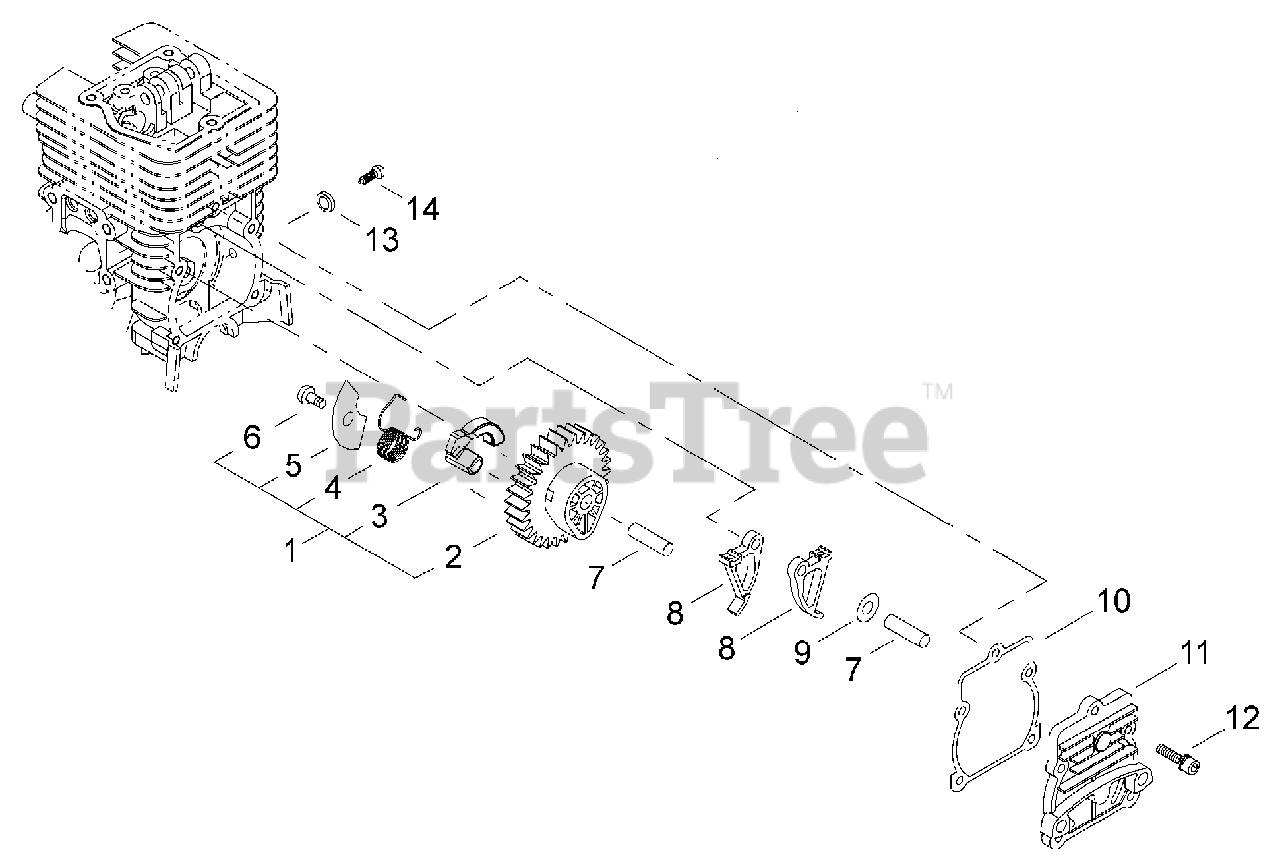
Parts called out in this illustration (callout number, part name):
1	CAM GEAR ASSY
2	GEAR, CAM
3	WEIGHT
4	SPRING
5	COVER, PLATE
6	SCREW - 4X6 -- TAPPING
7	PIN - LOCATING
8	FOLLOWER, CAM
9	WASHER - 5
10	GASKET
11	COVER, CAM GEAR
12	SCREW - 4X14
13	WASHER
14	SCREW - 5
